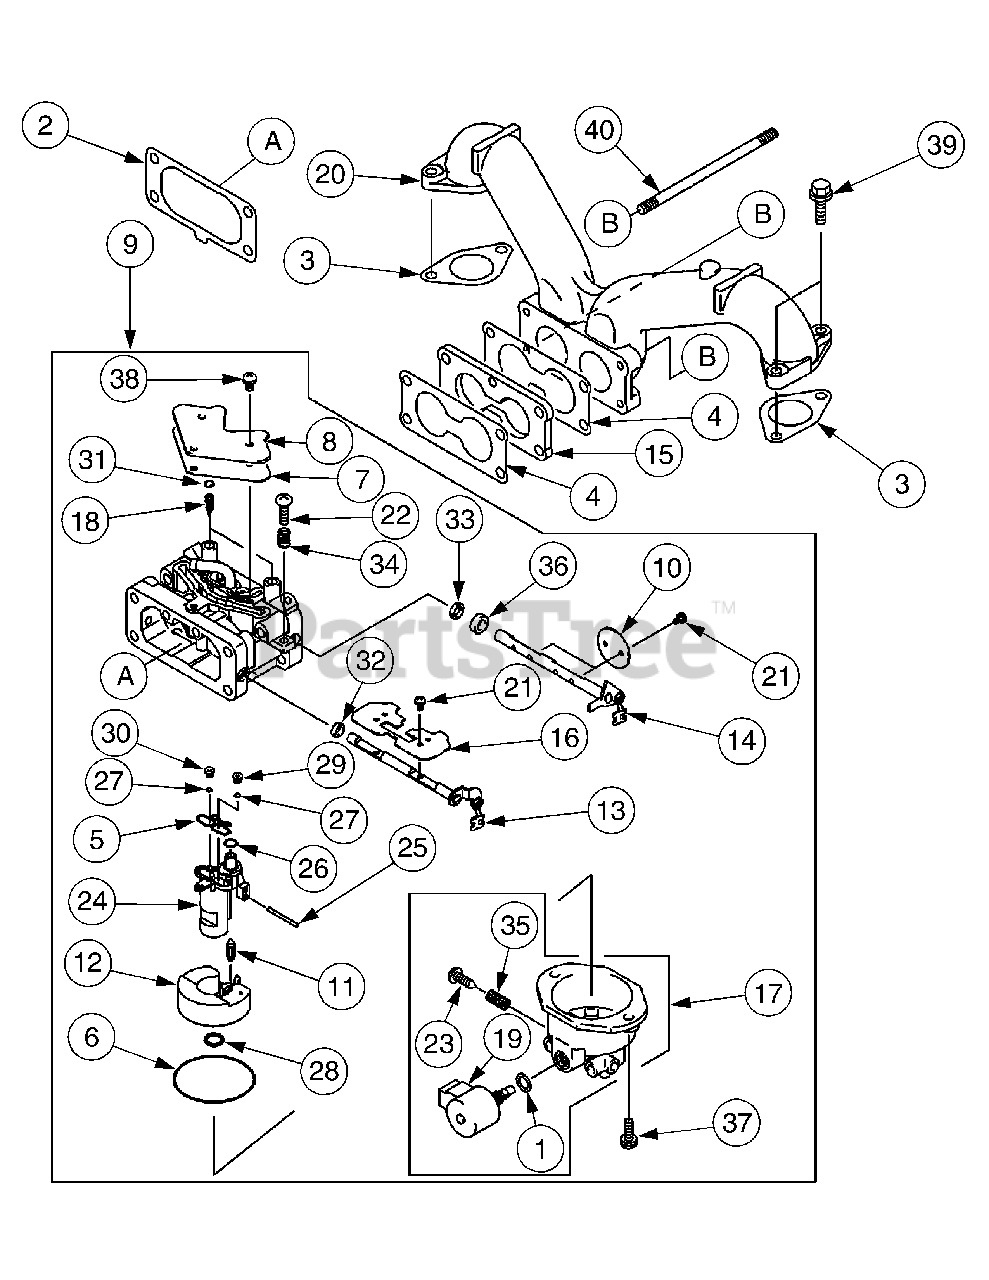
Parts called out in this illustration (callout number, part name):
2	Gasket, Air Filter
3	Gasket, Manifold
4	Gasket, Carburetor
9	Carburetor Assembly
10	Valve, Throttle
13	Shaft, Carburetor
14	Shaft, Carburetor
17	Chamber, Float
20	Manifold, Intake
24	Spacer
26	O-Ring
28	O-Ring
29	Jet, Main, #104
30	Jet, Main, #102
31	Plug, Expansion
32	Seal, D = 5.9
33	Seal, D = 6.9
39	Bolt, Flanged
40	Bolt, Stud
